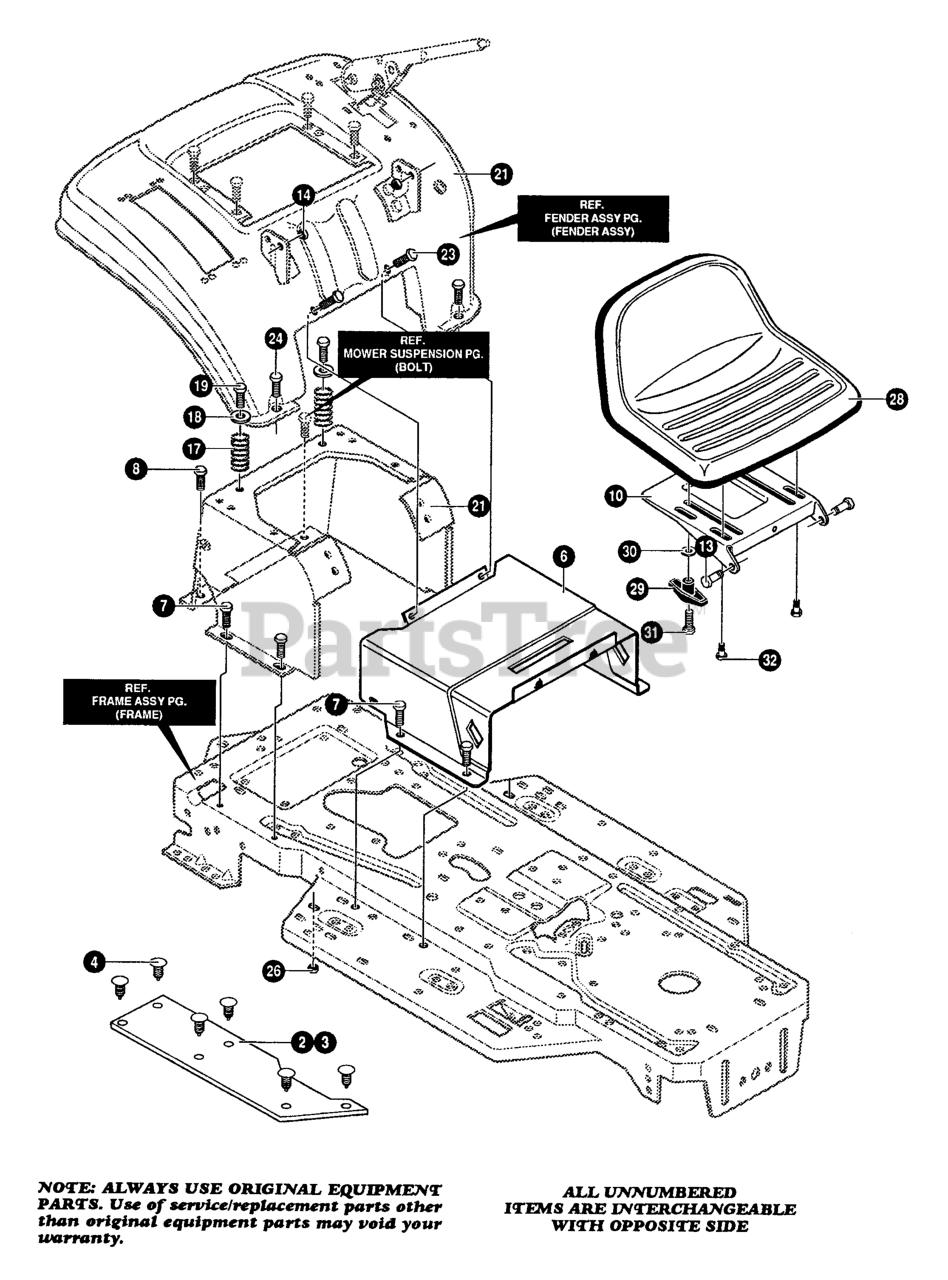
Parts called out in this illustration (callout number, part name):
2	FOOT PAD, LH
3	FOOT PAD, RH
4	FASTENER, RATCHET
6	CONSOLE, WALK-THRU
7	SCREW, 1/4-20 x .50
8	SCREW, 5/16-18 x 0.50
10	PLATE, SEAT
13	BOLT, .437 x .156
14	NUT, 5/16-18
17	SPRING, SEAT
18	WASHER, FLAT .281 x .63 x .065
19	SCREW, 1/4-20 x .50
21	FENDER
23	SCREW, 5/16-18 x 0.50
24	BOLT, 5/16-18 x 1.00
26	NUT, 5/16-18
29	HANDLE, WING NUT
30	WASHER, FLAT .344 x .69 x .065
31	SCREW, 5/16-18 x 1.00
32	BOLT, .500 x .10
